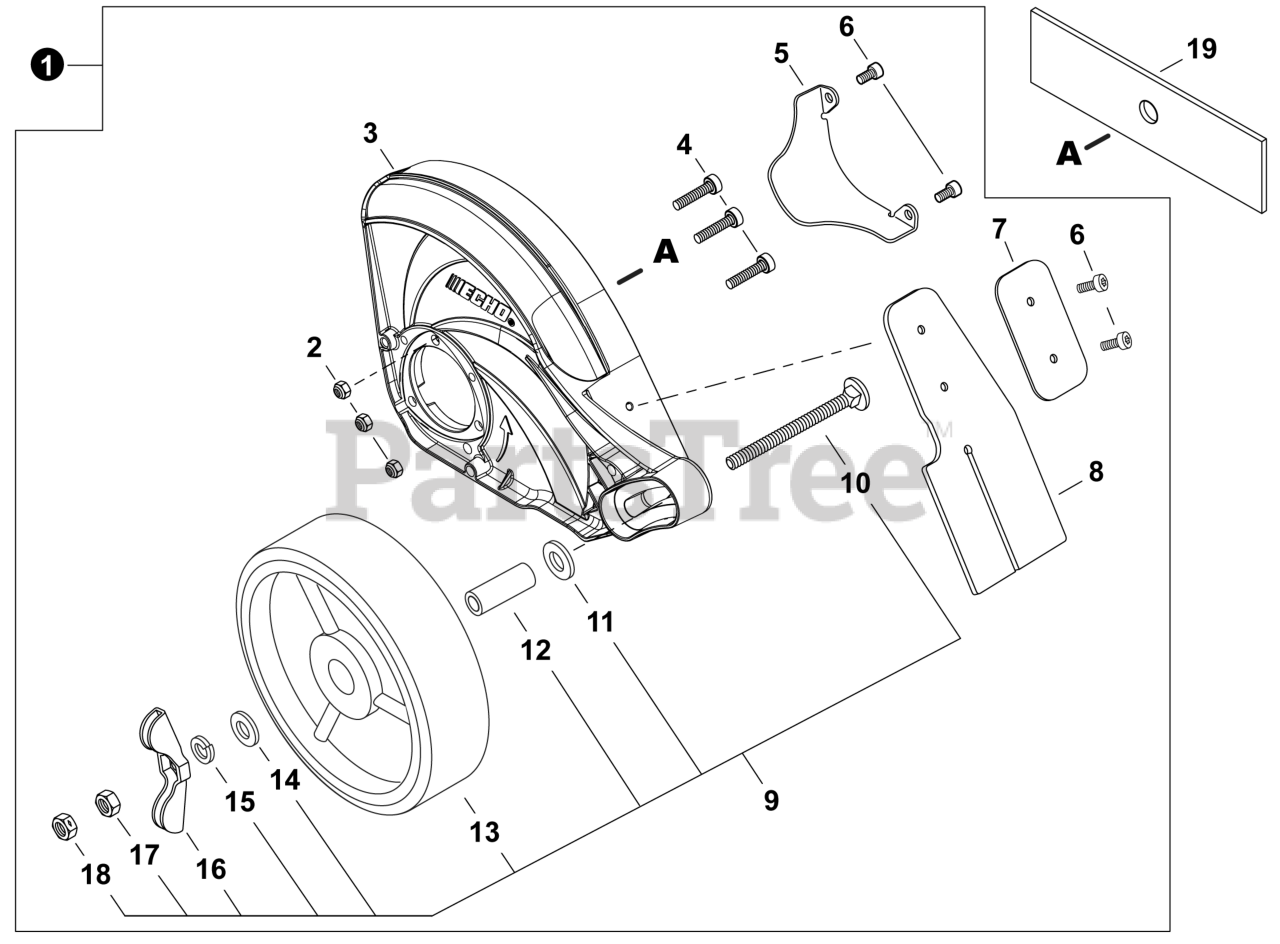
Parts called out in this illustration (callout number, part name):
1	SHIELD KIT, EDGER
2	NUT, LOCK M5
3	SHIELD, BLADE
4	BOLT, TORX 5x20
5	GUARD, SHIELD
6	BOLT, TORX 4x12
7	PLATE, FLAP
8	FLAP, DEBRIS
9	WHEEL KIT
10	BOLT M8-1.25x80 MM
11	WASHER M10
12	COLLAR 12
14	WASHER 8
15	WASHER, SPRING 8
16	KNOB, FASTENER
18	NUT, LOCK M8
19	BLADE - 2 PK
